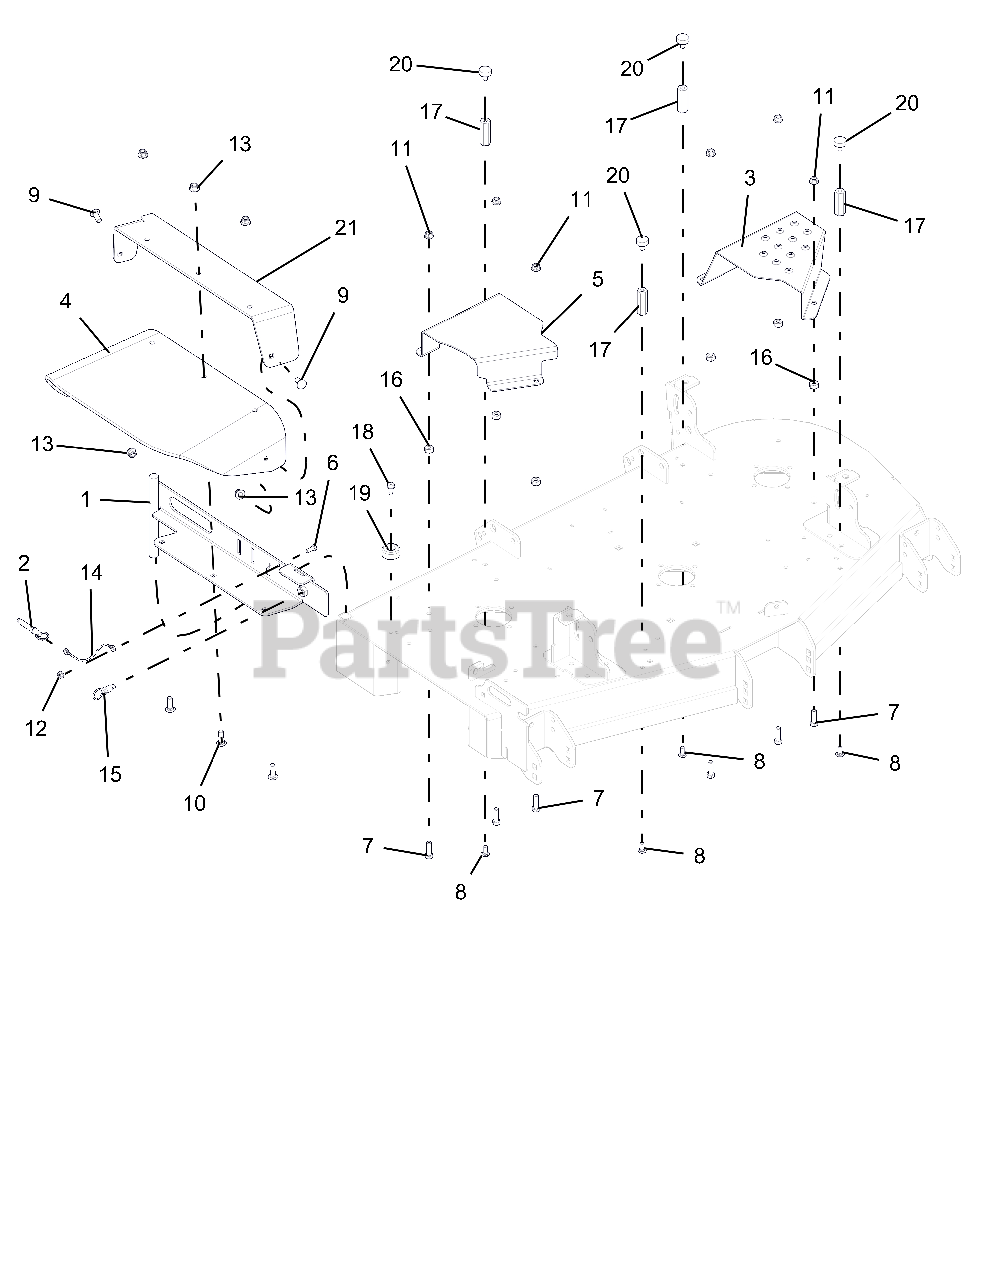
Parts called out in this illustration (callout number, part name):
1	WLDMT, 44"-48" DISCH CHUTE MTG-RED
2	PIN, SPRING BALL .375 OD X 1.50
3	GUARD, 44-52" LH DECK BELT-BLACK
4	CHUTE, RUBBER DISCHARGE
5	GUARD, 48"-52" RH DECK BELT-BLACK
6	BLT-HEX .25-20X.75 GR5 YWZC
7	BLT-HEX .38-16X1.25 GR5 YWZC
8	BLT, RDHDSQNK .31-18X.75 LOCTITE
9	BLT-RDHDSQNK .38-16X1.00 G5 YWZC
10	BLT-RDHDSQNK .38-16X1.25 G5 YWZC
11	@NUT-SPNLK-FLG .375-16 YWZC
12	NUT, LK-TOP-FLG .25-20 YWZC
13	NUT-LK-NYL-FLG .38-16 YWZC
14	CABLE, 6.0 LANYARD, NYLON
15	PULL PIN,.50-13THDX.310 PLNGR
16	NUT-HEAVY HEX .38-16 YWZC
17	NUT, .31-18 X 2.25 LG COUPLING
18	SCR-TAP .31-18X.75 HWH TR YWZ
19	BUMPER, RECESSED 1.50 X .63 W/.31 HOLE
20	BUMPER, RUBBER
21	DISCHARGE CHUTE SUPPORT W/SAFETY DECAL-RED
